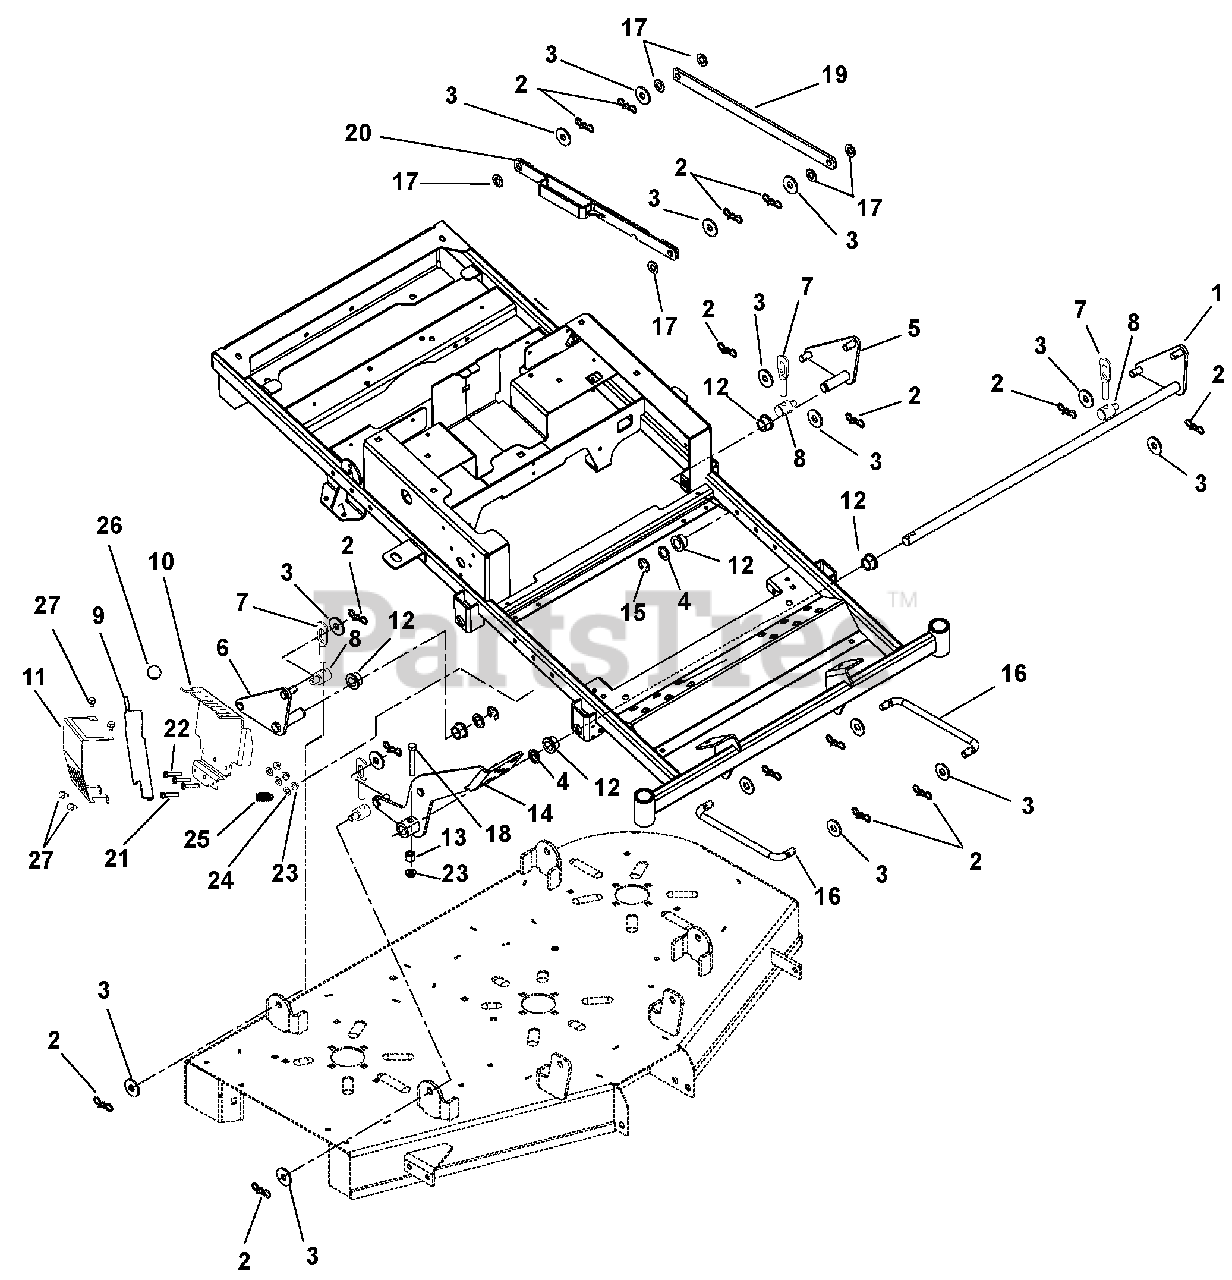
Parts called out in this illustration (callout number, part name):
1	WMT-DECK PIVOT FRONT
2	PIN,BOW TIE LOCKING .091X1.875
3	WSHR-FL-STL.511X1.441X.125 YWZ
4	WSHR-FL-STL.754X1.125X.062YWZC
5	WMT-DECK PIVOT ZTXL REAR LH
6	WMT-DECK PIVOT ZTXL REAR RH
7	DECK LINK
8	TRUNNION-.50
9	LEVER, HOC WLDMT XL
10	BRACKET, ADJUSTER HOC XL
11	GUARD, PLATE FIXED
12	BSHG-FLG .750X1.000X.625X1.250
13	BSHG-SLV .391X.688X.52 PM
14	WMT-ZTXL FOOT PEDAL
15	RG-RTNG-EXT .750X.050
16	LINK, DRAG
17	WSHR-FL-NYL .518X1.000X.080
18	@BLT-HEX .38-16X2.50 GR5 YWZC
19	LINK, LIFT
20	HOC, LINK RETAINING XL
21	@BLT-HEX .38-16X2.25 GR5 YWZC
22	@BLT-HEX .38-16X1.75 GR5 YWZC
23	@NUT-LK-NYL-FLG .38-16 YWZC
24	@WSHR-FL-STL.38X.875X.083 YWZC
25	SPRING, COMPRESSION
26	KNOB,BALL -BLACK 1.47" .375-16
27	SCR-TAP .25-20X.50 HWH TR YWZ
